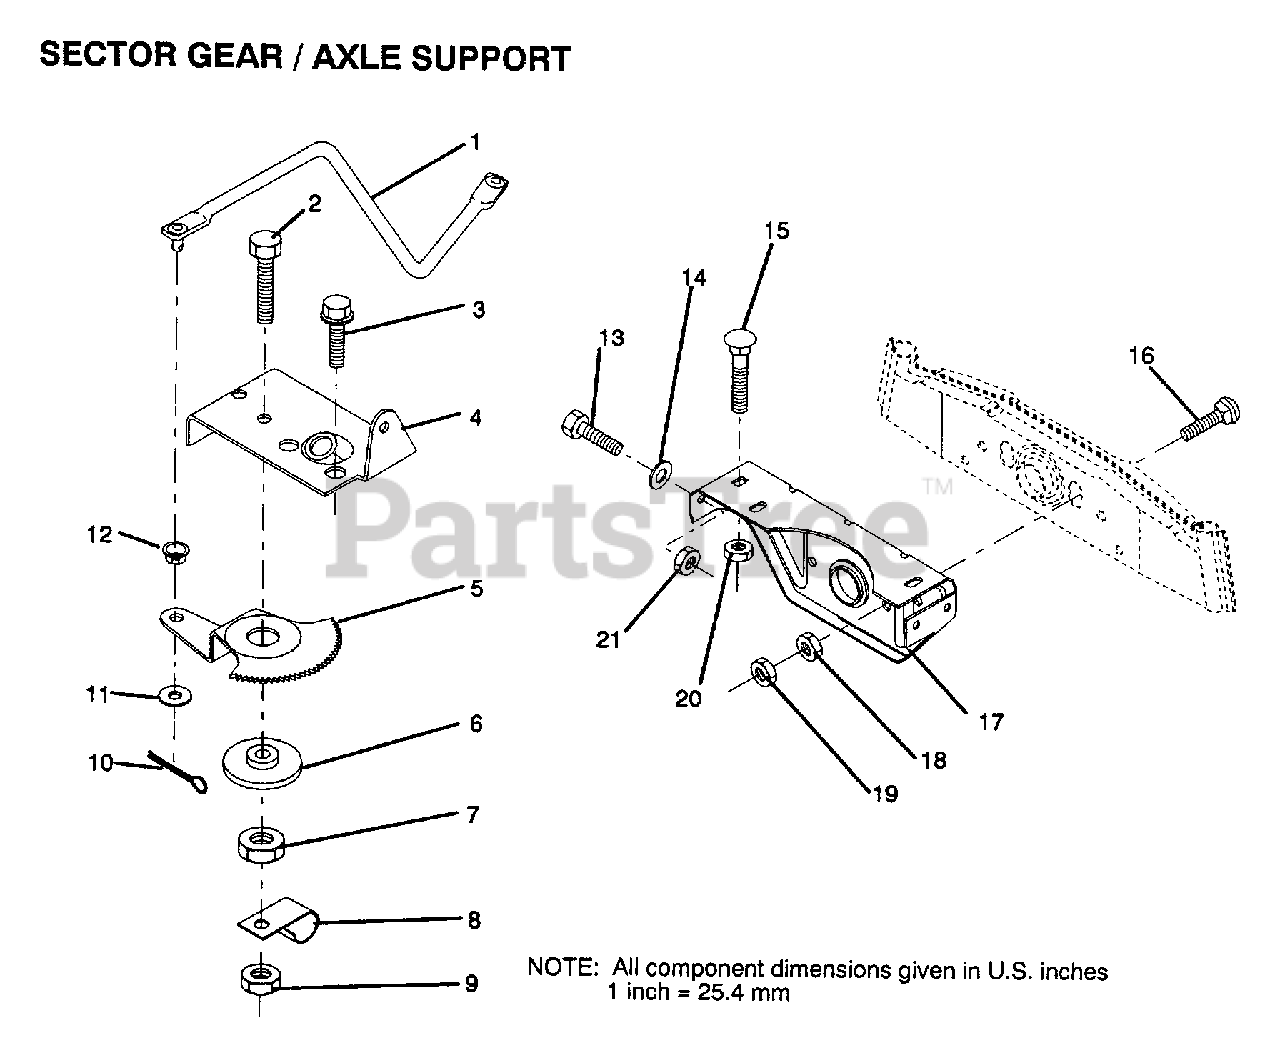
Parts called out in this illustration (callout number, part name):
2	"BOLT,HEX"
3	SCREW LT
4	"PLATE,STR SUPT"
5	GEAR SECTOR
6	BUSHING
7	NUT
8	CLIP INSULATOR
9	NUT LTV
10	COTTER PIN
11	WASHER
12	BUSHING.DRAGLINK
13	BOLT
14	WASHER
15	BOLT
16	BOLT
17	"SUPT,FRT AXLE"
18	NUT.HEX.3/8-16UNC
19	LOCKNUT
